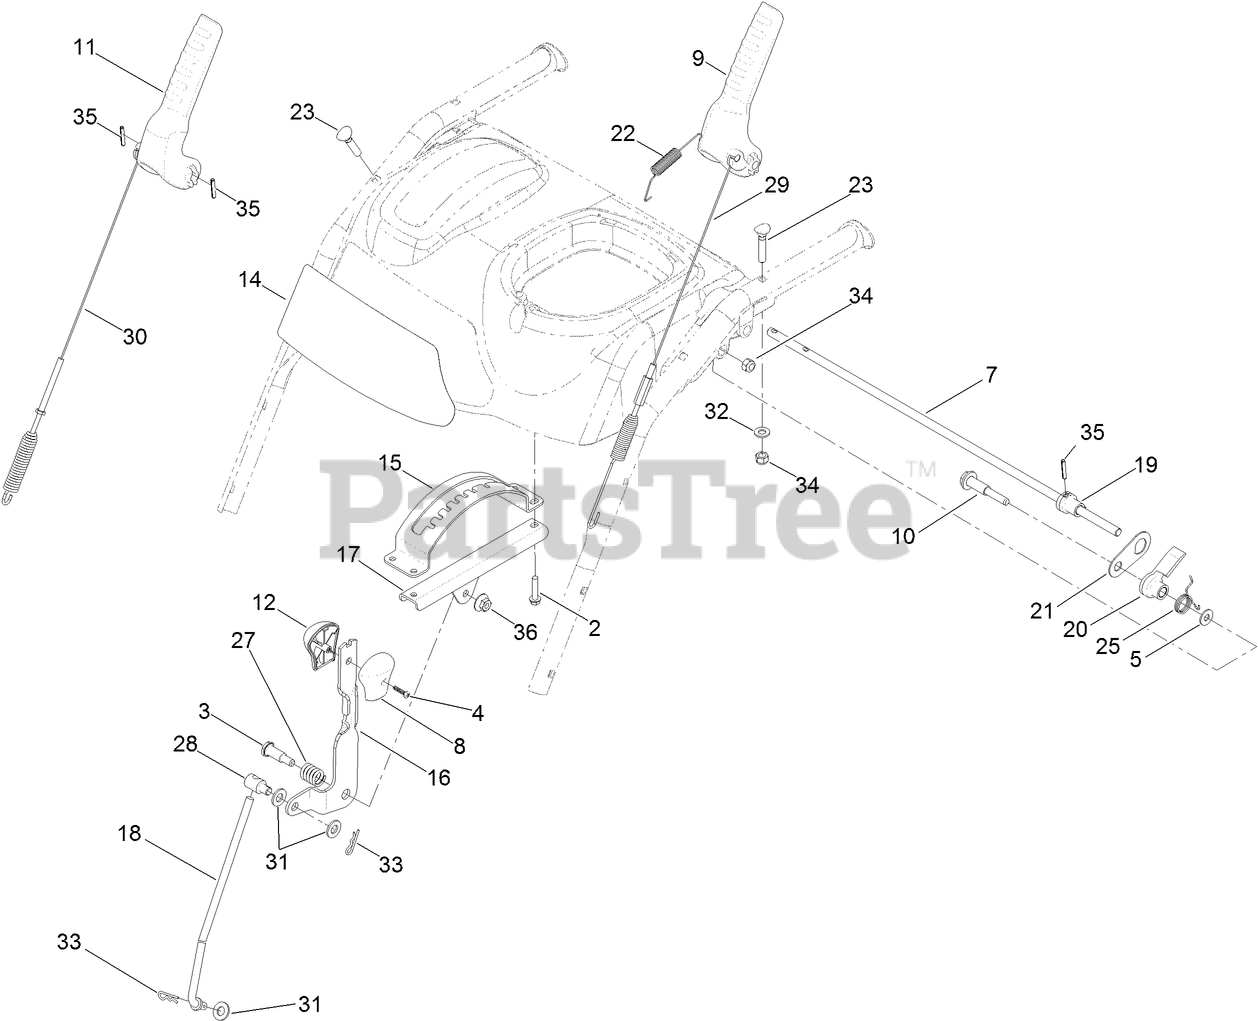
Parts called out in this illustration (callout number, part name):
2	SCREW-PLASTITE
3	SCREW-SHOULDER
4	SCREW-PPH
5	WASHER-FLAT
7	ROD-LOCKOUT
8	KNOB-SHIFT, LH
9	LEVER-TRACTION
11	LEVER-AUGER
12	KNOB-SHIFT, RH
14	DECAL-CONTROL PANEL
15	GUIDE-SELECTOR, SPEED
16	SELECTOR-SPEED
17	MOUNT-SELECTOR, SPEED
19	CAM-LOCKOUT
20	LATCH-LOCKOUT
21	LINK-LOCKOUT
22	SPRING-TENSION
23	SCREW-HANDLE
25	SPRING-TORSION
28	TRUNNION-ROD
29	CABLE-TRACTION
30	CABLE-AUGER
31	WASHER-FLAT
32	WASHER-FLAT
34	NUT-LOCK, NI
35	PIN-SPRING
36	NUT-HF
